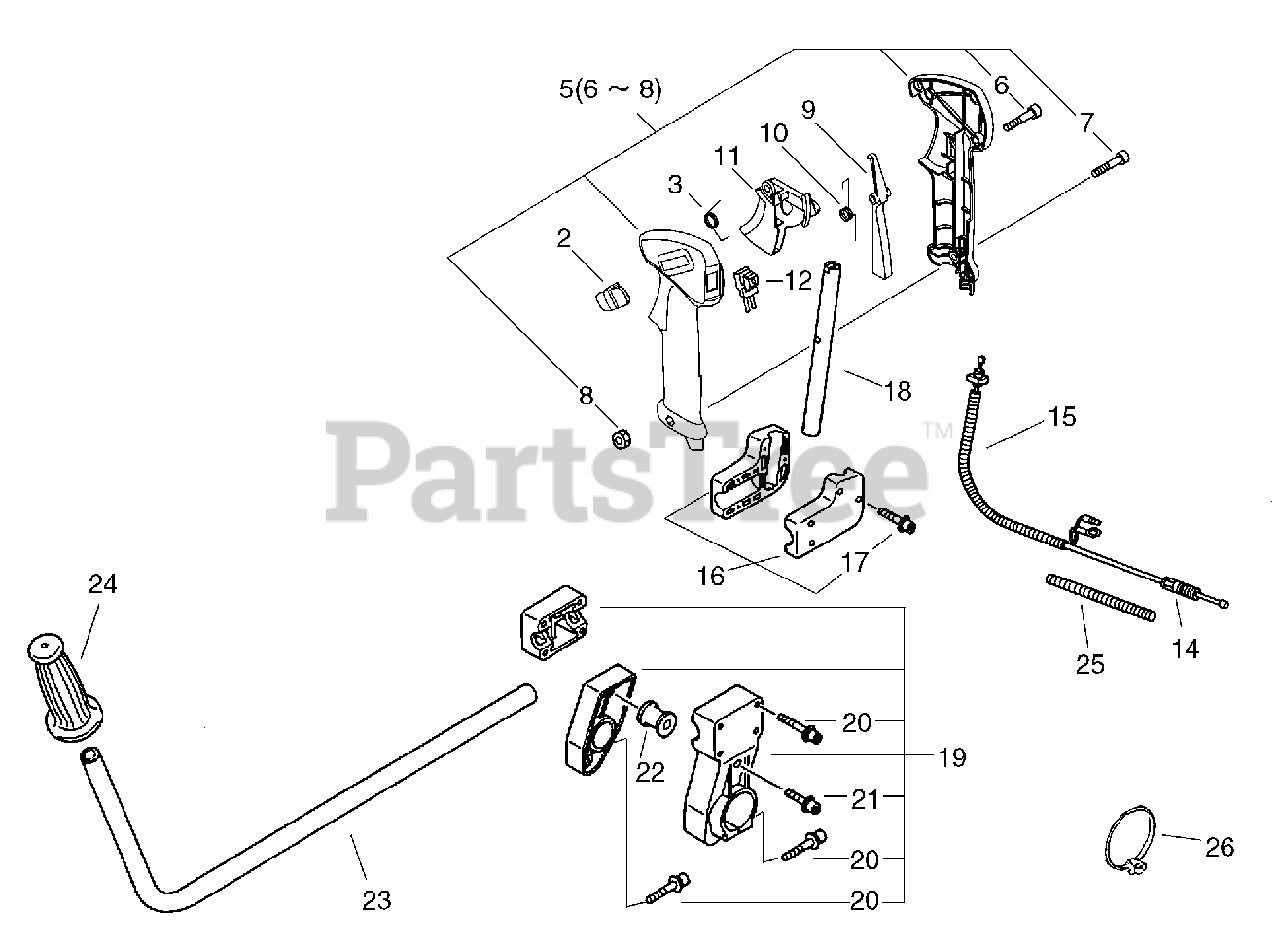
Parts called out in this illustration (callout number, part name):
2	LATCH, THROTTLE
3	SPRING, TORSION
5	GRIP ASSY, THROTTLE
6	SCREW 4×16
7	SCREW 5×30
8	NUT M5
9	LOCKOUT, THROTTLE
10	SPRING, TORSION
11	TRIGGER, THROTTLE
12	SWITCH, ON-OFF
14	CABLE, THROTTLE
16	BRACKET, HANDLE
17	BOLT 5×25
18	HANDLE, REAR
19	BRACKET ASSY, HANDLE
20	BOLT M5×35
21	BOLT 5×14
23	HANDLE, FRONT
26	BAND
